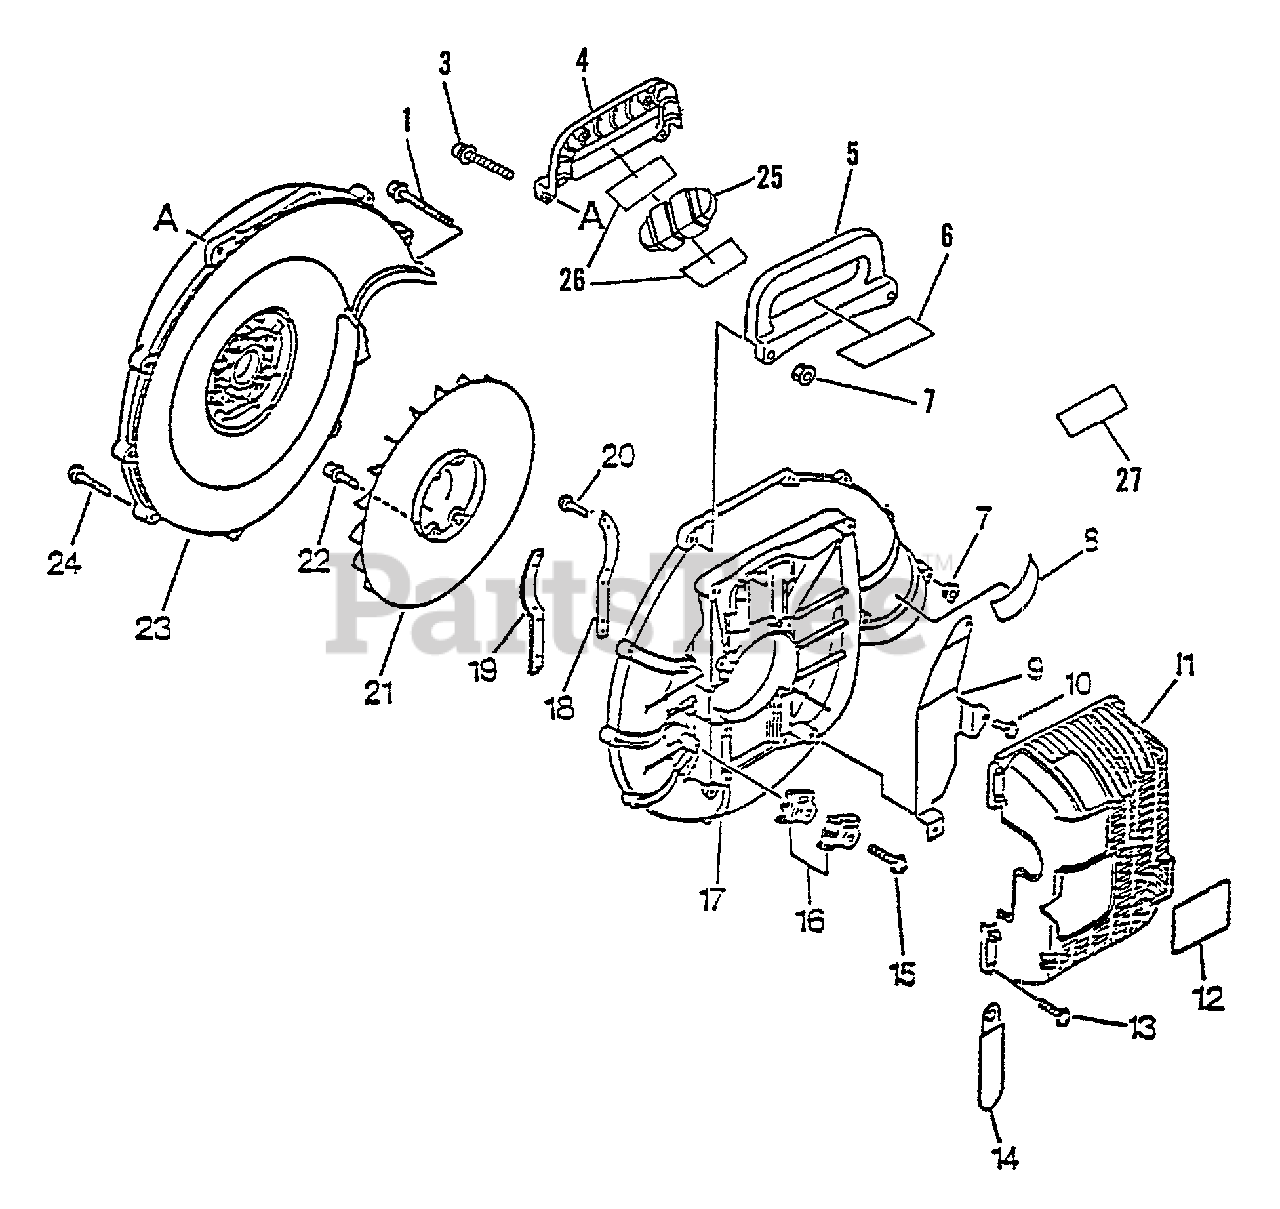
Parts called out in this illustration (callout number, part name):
1	SCREW - 5X60
3	SCREW - 5X45
5	HANDLE - REAR
6	LABEL - CAUTION
7	NUT - 5 -- FLANGE
8	LABEL - MODEL
9	INSULATOR
10	SCREW - 5X20
11	COVER, ENGINE
12	LABEL - MODEL LBB-4200
13	SCREW - 5X20
15	SCREW - 5X25
16	CABLE HOLDER KIT
17	COVER, FAN - OUTER
18	BRACKET, ENGINE
19	BRACKET, ENGINE
20	SCREW - 3X8
22	SCREW - 5X20
23	COVER, FAN - INNER
24	SCREW - 5X30
25	WEIGHT, HANDLE
27	LABEL - NOISE
